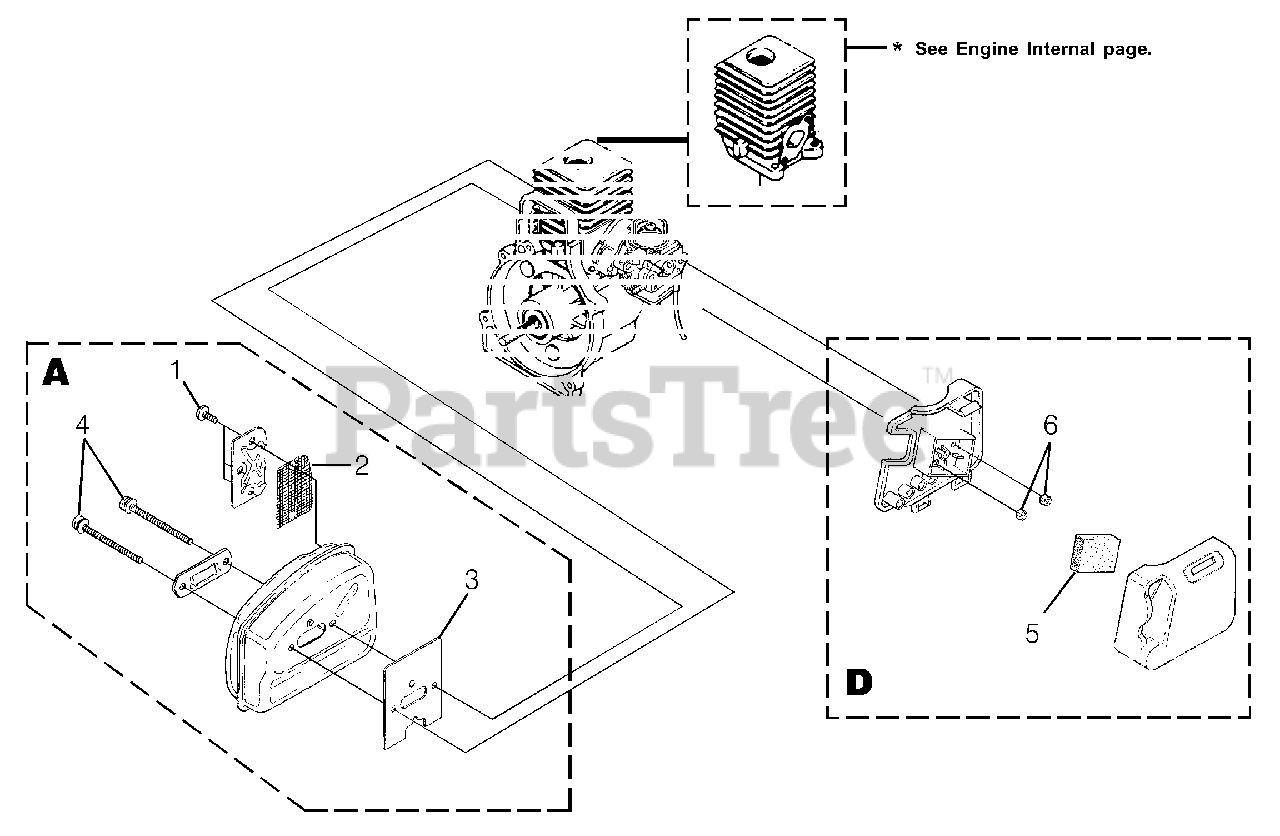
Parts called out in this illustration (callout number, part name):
1	SCREW, Taptite- (8-32 X 3/8")
2	SCREEN-Spark
3	GASKET-Muffler
4	SCREW, Truss Hd. - (10-24 X 2.188)
5	FILTER-AIR
6	NUT-Hex (10-24)
A	MUFFLER ASSY.
D	AIR FILTER KIT
